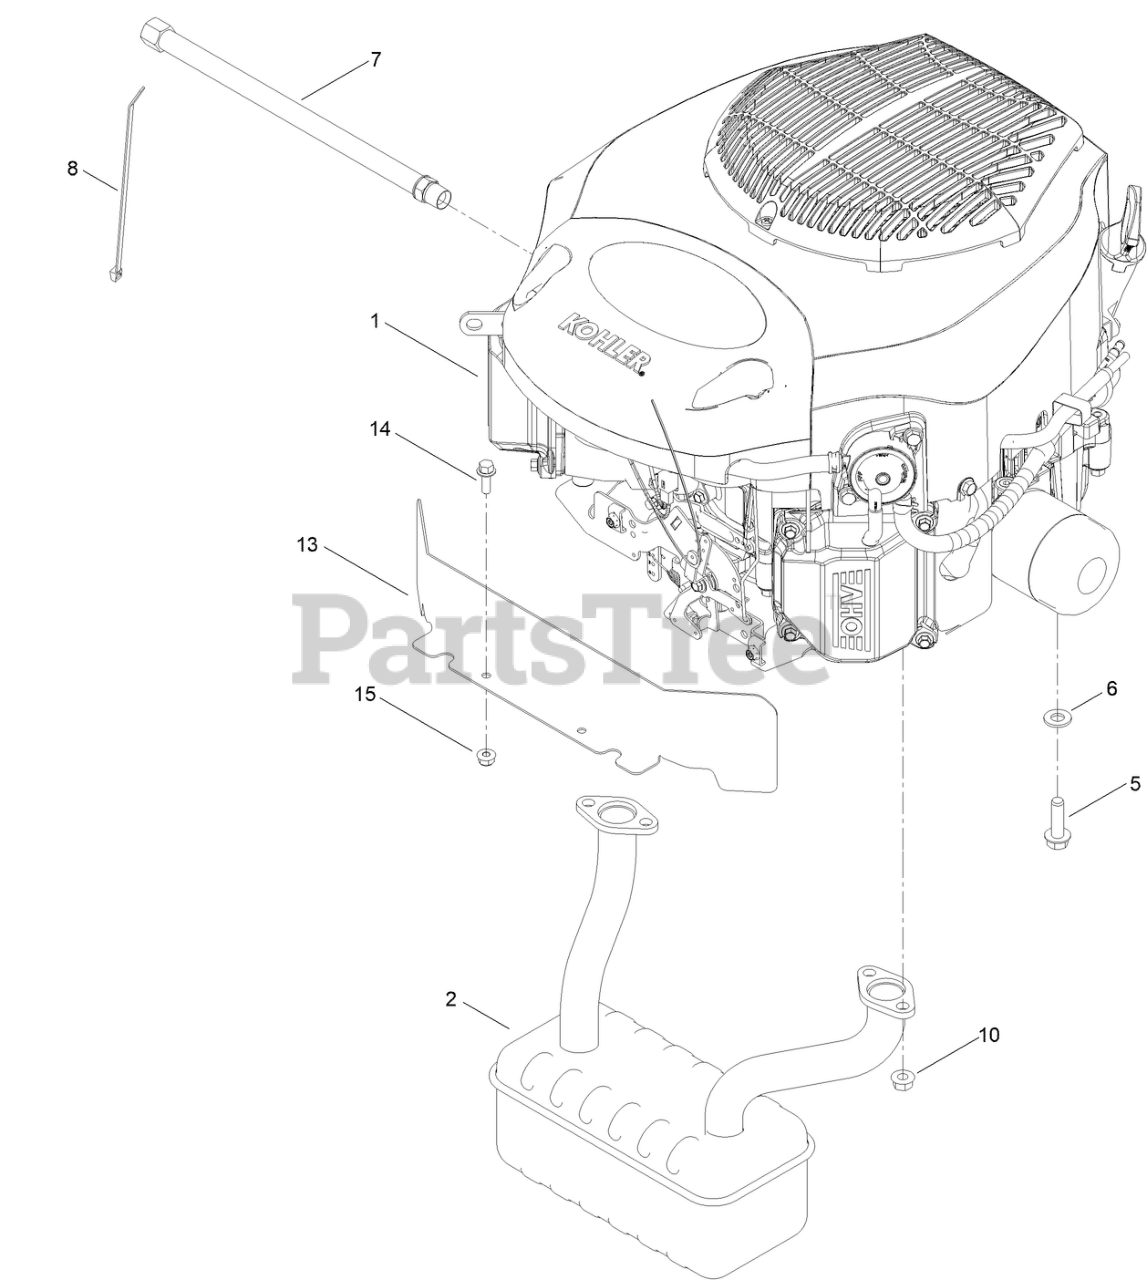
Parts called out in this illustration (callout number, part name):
1	ENGINE-KOHLER, KT735 LOW SPEED
2	MUFFLER
5	SCREW-HWH, THD ROLL
6	WASHER-FLAT
7	HOSE-DRAIN, OIL
8	TIE-CABLE
10	NUT-HF
13	SHIELD-HEAT
14	SCREW-HHF
15	NUT-FLANGE, NI
